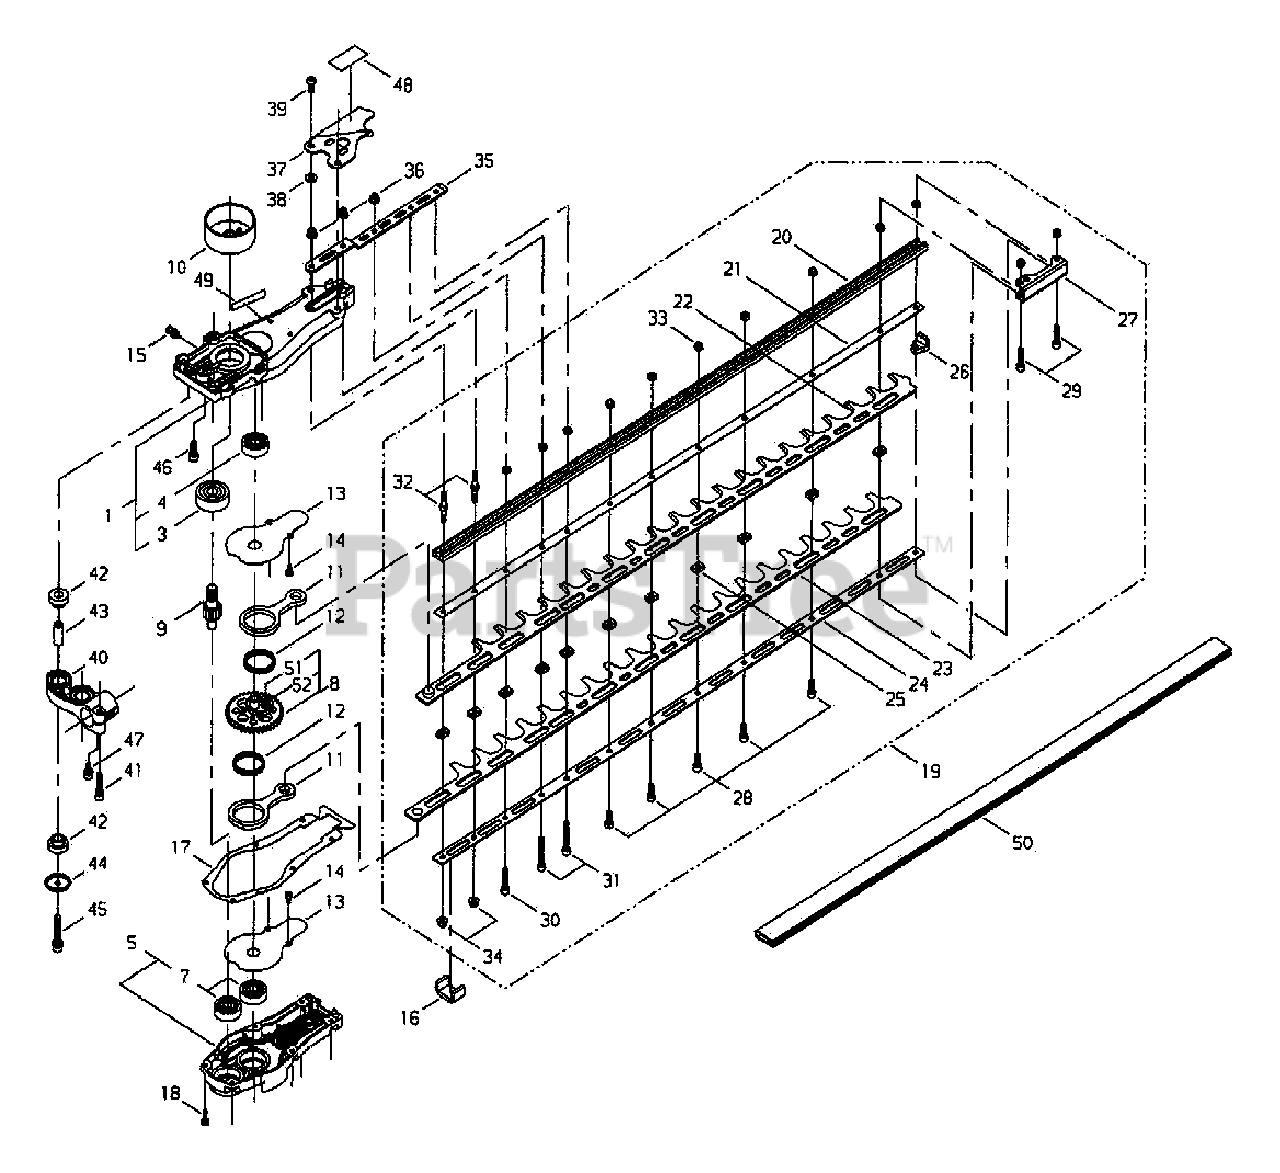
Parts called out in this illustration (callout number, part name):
1	GEAR CASE HOUSING ASSY
3	BEARING, BALL 6301 DDU
4	BEARING, BALL 6200ZZ
5	COVER ASSY, GEAR CASE
7	BEARING, BALL 6200ZZ
8	CAM GEAR ASSY
9	PINION
10	DRUM, CLUTCH
11	CONROD
12	BEARING, NEEDLE 30
13	PLATE, GEAR CASE
14	BOLT 4×8
15	FITTING, GREASE
16	PACKING, FELT
17	GASKET, GEAR CASE
18	BOLT 4×14
19	TRIMMER BLADE KIT - 30"
20	GUIDE BAR, 30"
21	PLATE, UPPER
22	BLADE, UPPER 30"
23	BLADE, LOWER 30"
24	PLATE, LOWER
25	SPACER
26	BLOCK
27	PLATE, GUIDE
28	BOLT 5×14
29	BOLT 5×20
30	BOLT 5×25
31	STUD, MOUNTING M5
32	BOLT M5×35
33	NUT, LOCK M5
34	NUT M5
35	BRACKET, CUTTER
36	NUT M5
37	PROTECTOR
38	WASHER M5
39	BOLT M6×12
40	MOUNT, HANDLE
41	BOLT M5×25
42	CUSHION
43	COLLAR 6
44	WASHER 6
45	BOLT M6×35
46	BOLT 6×16
47	BOLT M5×12
48	LABEL, WARNING
49	LABEL, LUBE BLADES
50	SCABBARD 30"
51	BOLT M5×6
52	CAM
